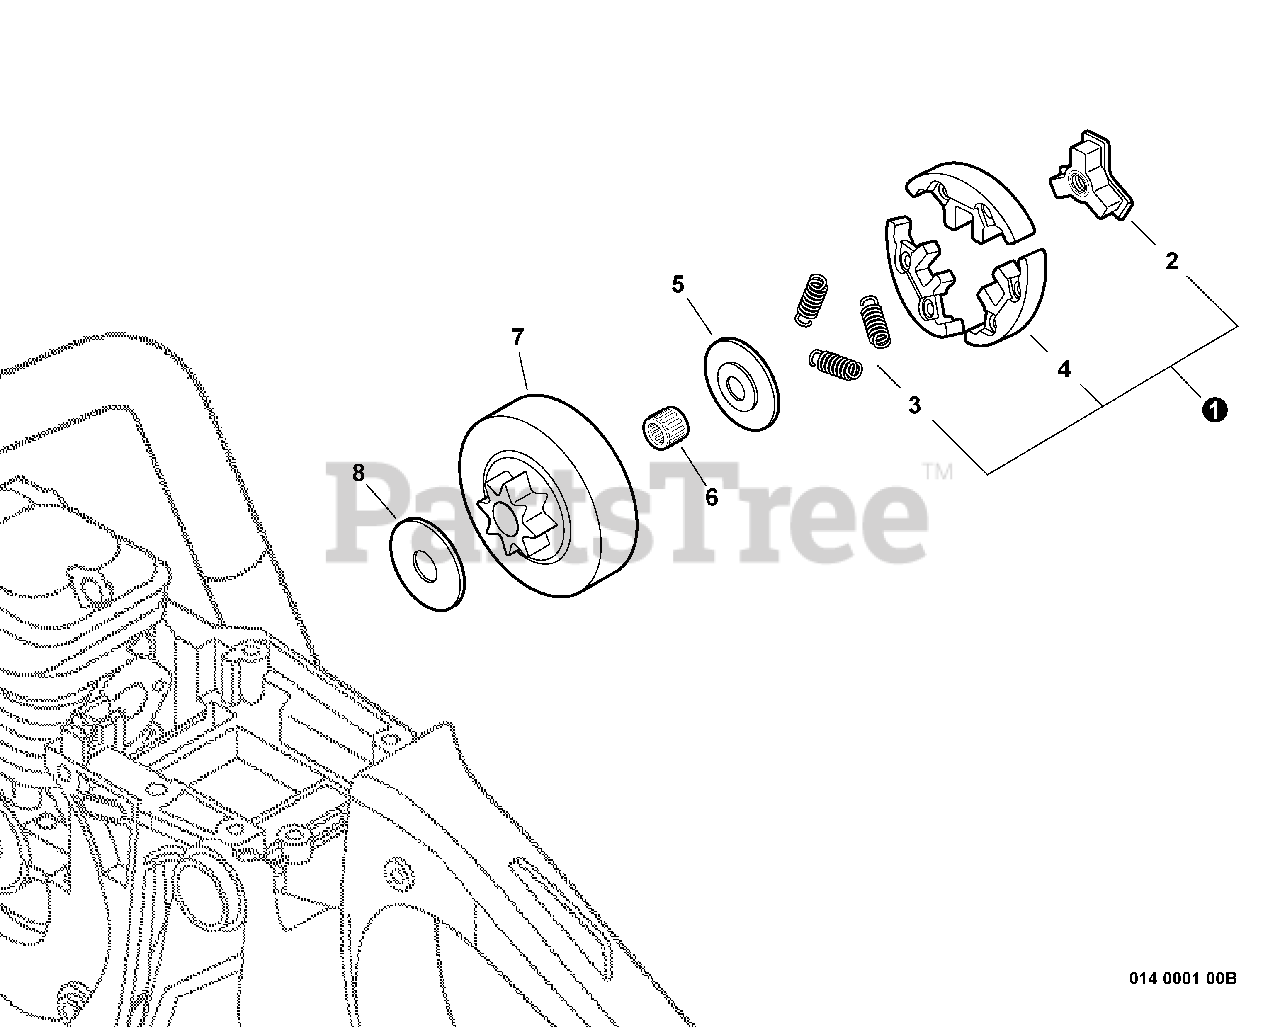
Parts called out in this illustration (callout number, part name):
1	CLUTCH ASSY
2	HUB, CLUTCH
3	SPRING, TENSION
4	SHOE SET, CLUTCH (3PCS)
5	PLATE, CLUTCH
6	BEARING, NEEDLE 10
7	DRUM, CLUTCH
8	WASHER 10.2×24.5×1.2
